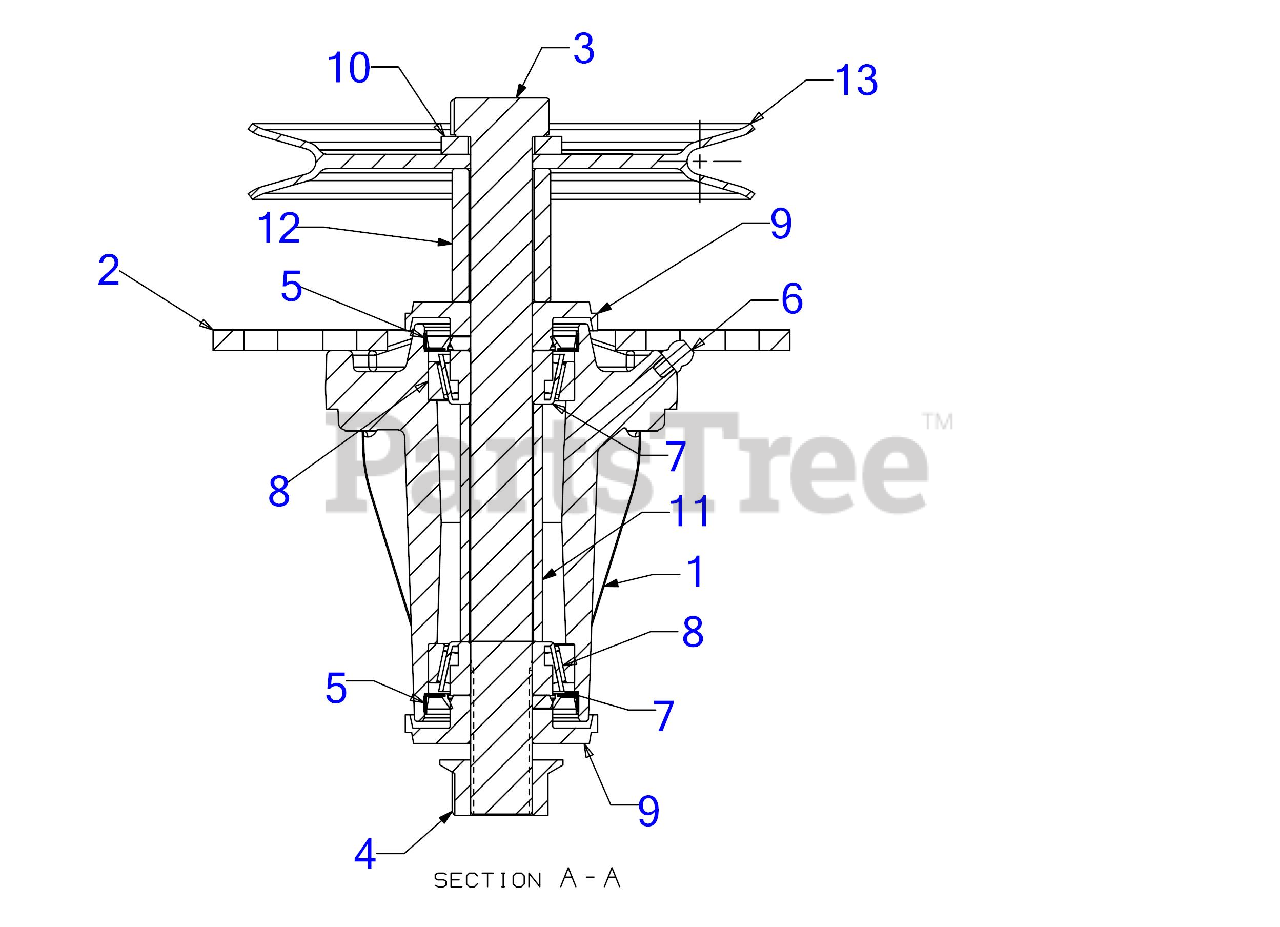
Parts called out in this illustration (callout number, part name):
1	HOUSING
3	SCREW 3/4-16 x 8.25 GR5
4	HEX FLANGE NUT 3/4
5	SINGLE LIP SEAL
6	GREASE FITTING
7	BEARING CONE
8	BEARING CUP
9	DECK SPINDLE SPACER
10	SPACER .812 ID x .218 LG
13	V-PULLEY 6.107 DIA
